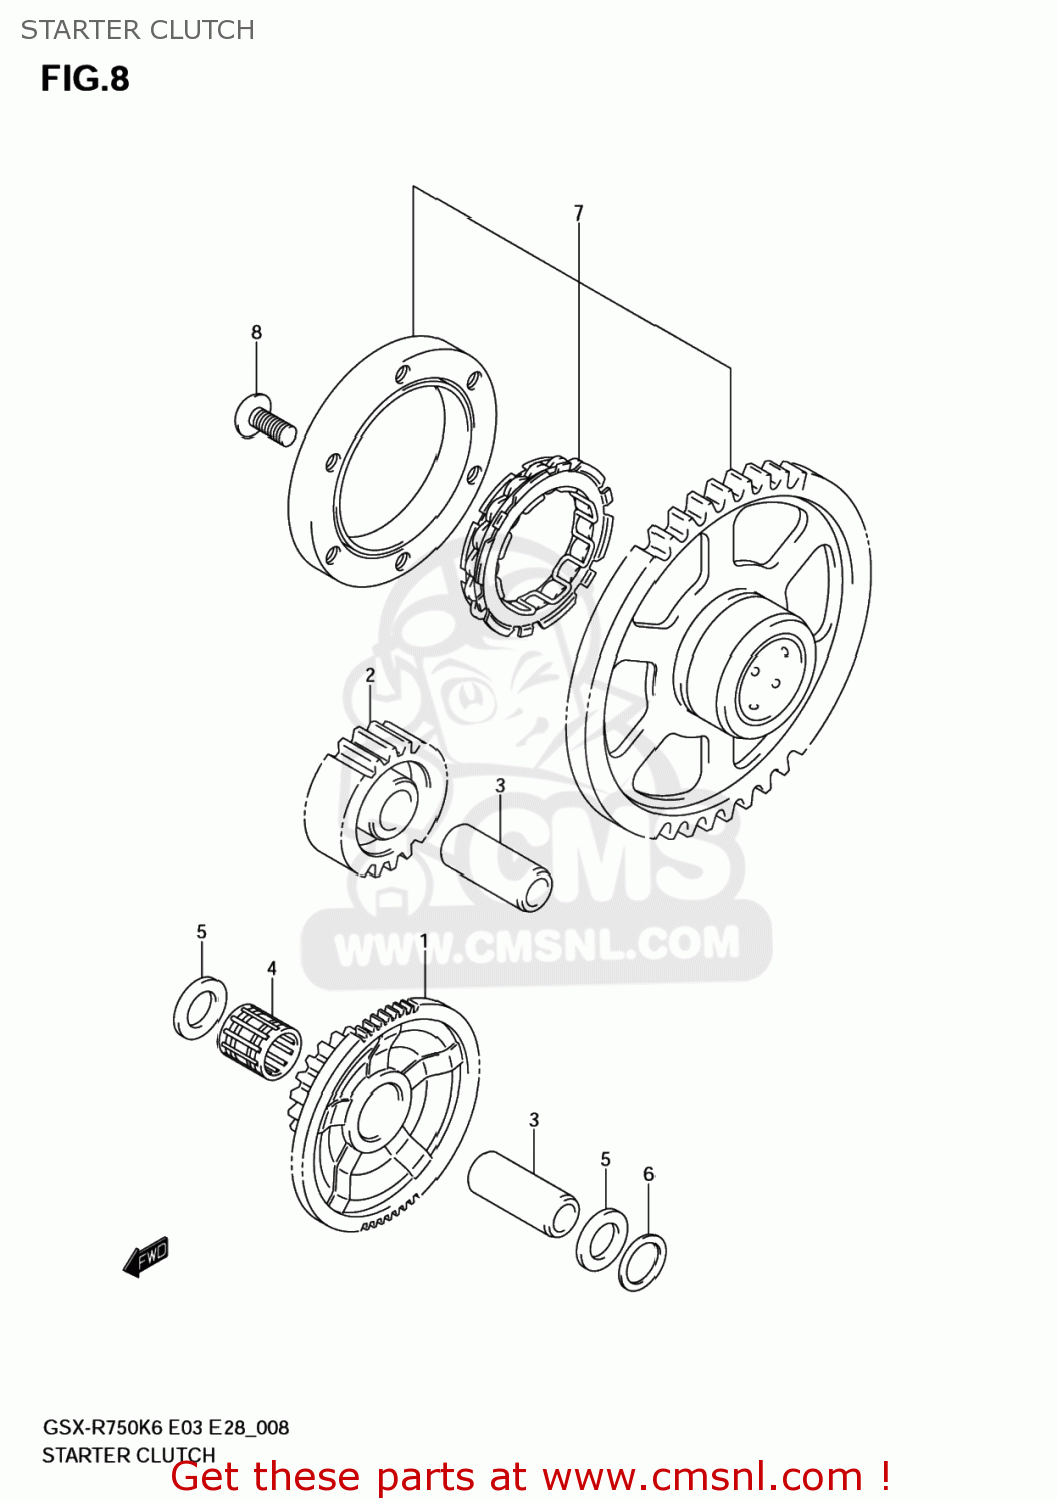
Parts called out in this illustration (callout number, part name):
1	GEAR,STARTER IDLE NO.1
2	GEAR,STARTER IDLE NO.2
3	PIN(8X12X33)
4	BEARING(12X16X16)
5	SHIM(12X20X1)
6	WASHER
7	CLUTCH SET,STARTER
8	BOLT (6X13)
